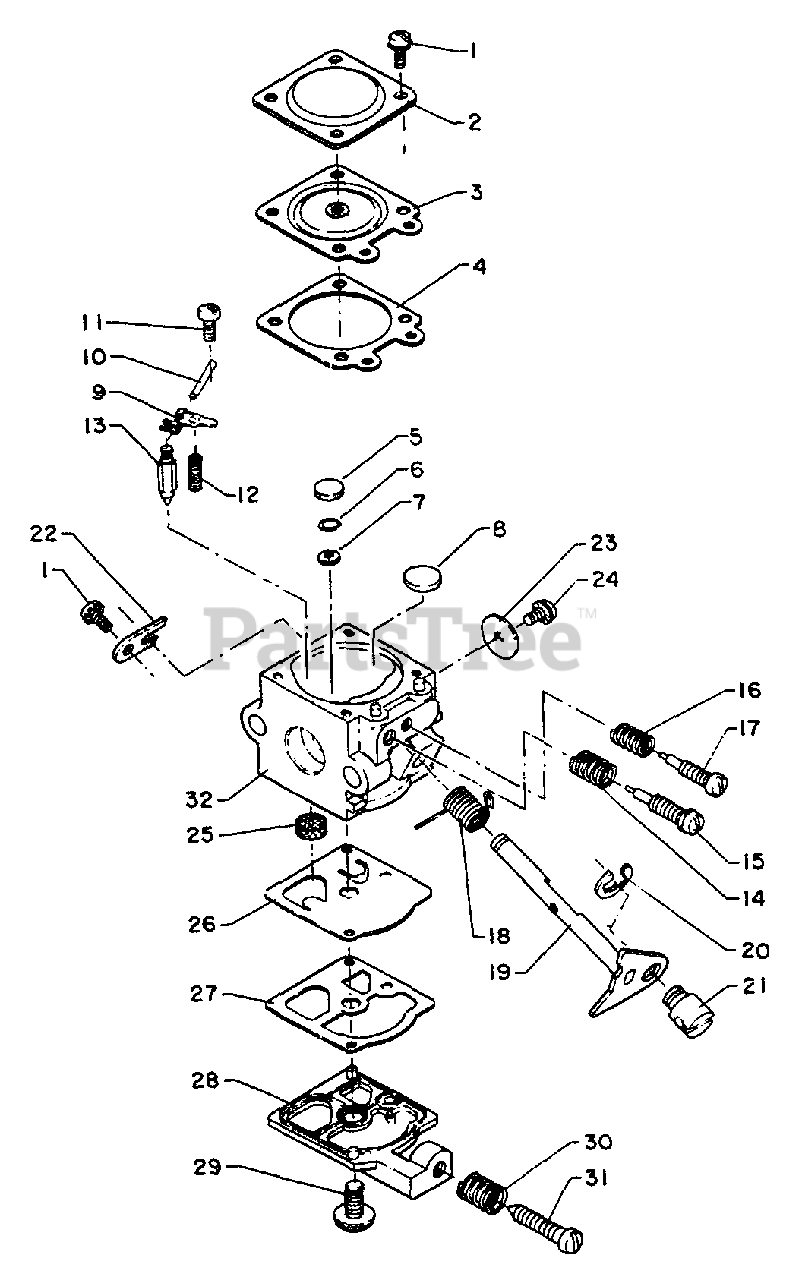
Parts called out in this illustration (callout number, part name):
2	COVER, METERING DIAPHRAGM
3	DIAPHRAGM, METERING
4	GASKET, METERING
5	PLUG, WELCH
6	RING, RETAINING
7	SCREEN, SPARK ARRESTER
8	PLUG, WELCH
9	LEVER, METERING
10	PIN, METERING LEVER
11	SCREW, METERING LEVER PIN
12	SPRING, METERING LEVER
13	VALVE, INLET NEEDLE
14	SPRING, HIGH NEEDLE
15	NEEDLE, HIGH SPEED
16	SPRING, NEEDLE
17	NEEDLE, IDLE
18	SPRING, THROTTLE RETURN
19	SHAFT, THROTTLE
20	RING, RETAINING
22	CLIP, THROTTLE SHAFT
23	VALVE, THROTTLE
25	SCREEN, FUEL INLET
26	DIAPHRAGM, PUMP
27	GASKET, PUMP
28	COVER, PUMP
31	SCREW, IDLE ADJUST
32	BODY, CARBURETOR
